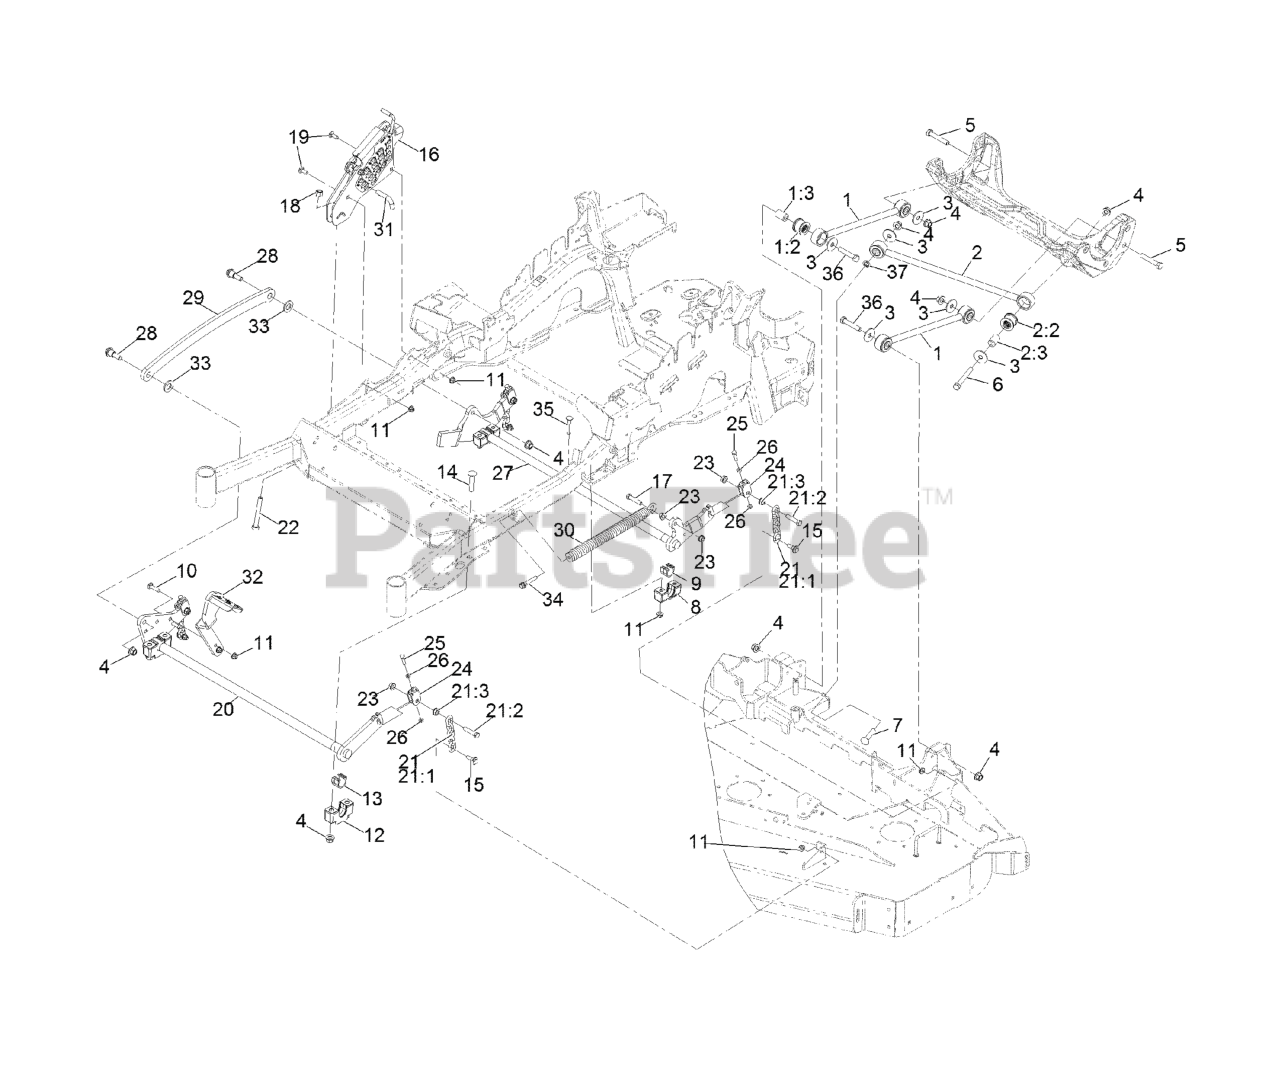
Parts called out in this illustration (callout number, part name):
1	DECK STRUT ASM
1:2	BUSHING-SUSPENSION, RUBBER
2	PANHARD ROD ASM
2:2	BUSHING-SUSPENSION, RUBBER
3	WASHER-THRUST
4	Nut-Lock 1/2-13
5	SCREW-HH
6	SCREW-HH
7	SCREW-CARR
8	SUPPORT-CROSS SHAFT, BEARING REAR
9	BEARING-CROSS SHAFT, REAR
10	SCREW-CARR
11	NUT-HF, NI
12	SUPPORT-CROSS SHAFT, BEARING
13	BEARING-CROSS SHAFT, FRON
14	Bolt-Carriage 1/2-13 X 2 1/2 Spl Neck
15	SCREW-SHOULDER, HHF
16	HOC ASM
17	SCREW-HH
18	NUT-LOCK, NI
19	BOLT-CARR
20	DECKLIFT-FRONT
21	DECK LIFT CHAIN ASM
21:1	CHAIN-LIFT, DECK
21:2	SCREW-HH
22	BOLT-TAP
24	YOKE-ADJUST, DECK
25	SCREW-HH
26	NUT-JAM
27	LIFT-DECK, REAR
28	SCREW-SHOULDER, HHF 1/2-13 X 1.12
29	LINK-LIFT, DECK
30	SPRING-EXTENSION
31	PIN-HOC
32	LEVER-FOOT
33	WASHER-FLAT
34	BOLT-SHOULDER
35	Bolt-Carriage 3/8-16 X 2 1/4
36	SCREW-HH
37	NUT-PUSH
